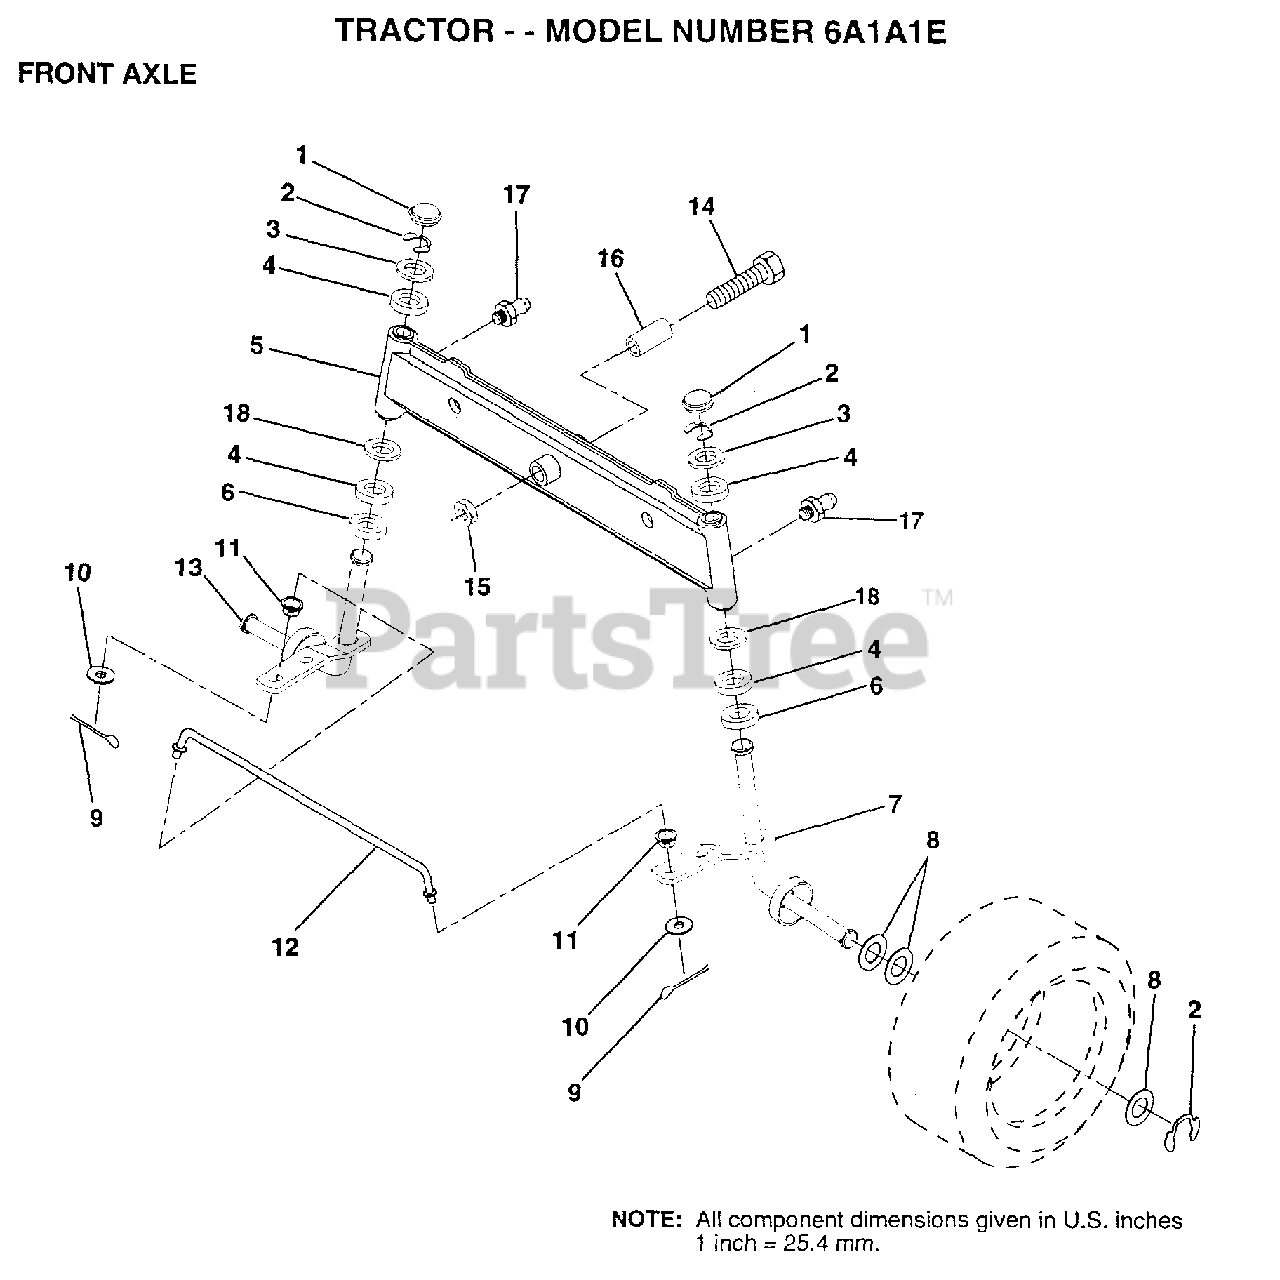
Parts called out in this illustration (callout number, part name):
1	CAP
2	RING
3	WASHER
4	COL. SRTG. BEAR.
5	AXLE ASM FRONT
6	WASHER .T
7	SPINDLE ASM RH
8	WASHER
9	COTTER PIN
10	WASHER
11	BUSHING.DRAGLINK
12	TIE ROD
13	SPINDLE ASM LH
14	BOLT HEX 5/8-11
15	"NUT-LOC,FLANGE LT"
16	BEARING
17	ZERK M
18	WASHER
